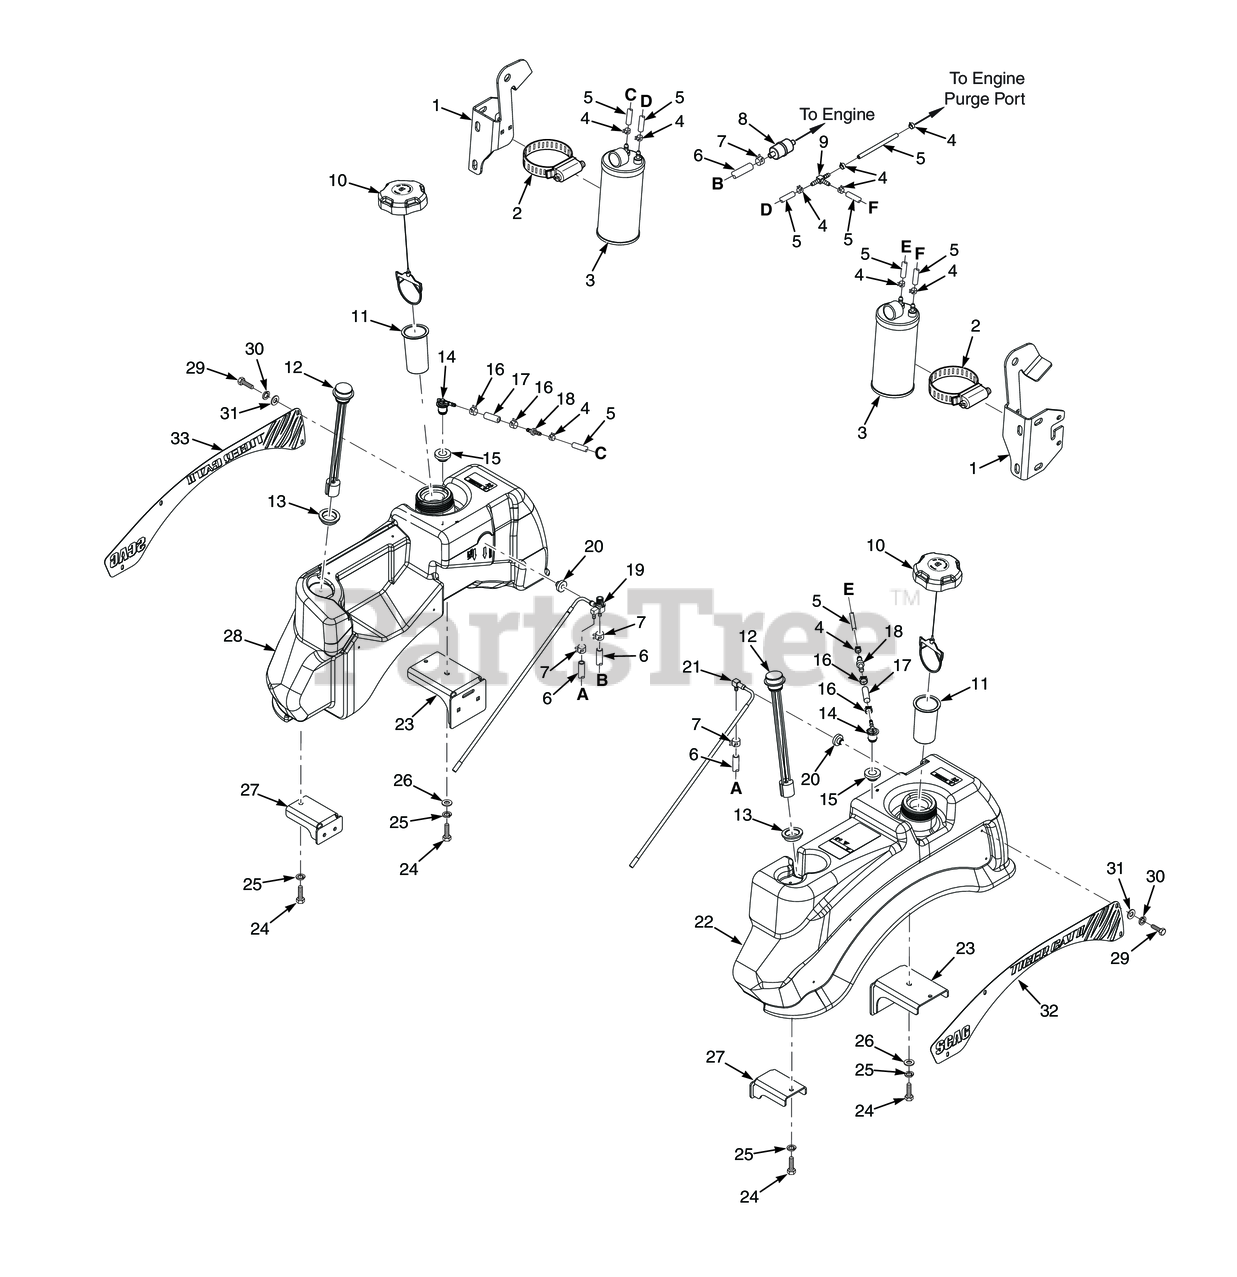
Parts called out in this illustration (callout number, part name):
1	ROPS Mount, LH
1	ROPS Mount, RH
2	Clamp, 3-1/2" Max. Dia.
3	Carbon Canister - SVR-36A / SVR-48V
4	Clamp, Vapor Recovery Hose 3/16"
5	Hose, Vapor Recovery 3/16" (order by inch)
6	Fuel Hose, 1/4" I.D. Non-Perm (791DFI Fuel Return) - Order by Inch
7	Clamp, Fuel Hose 1/4" Hose I.D.
8	Fuel Filter
9	Tee, 3/16 x 3/16 x 3/16 Union, Hose Barb
10	Fuel Cap w/ Tether (E.P.A.)
11	Tube, Fuel Tank Insert - 4"
12	Fuel Gauge Assembly
13	Grommet, Fuel Gauge
14	Remote Vent, No Valve
15	Grommet, Viton,
16	CLAMP, FUEL HOSE(KAWASAKI ONLY)
17	Hose, 1/4" Vapor Recovery (order by inch)
18	Mender, 1/4 x 3/16 w/0.02 Hole
19	Fuel Tube Assembly, Includes Valve
20	Bushing, 0.56" Dia. Viton
21	Fuel Tube Assembly, LH
22	Fuel Tank Assembly, LH (incl. # 12, 14, 15, 20, 21, 29, 30, 31, 32)
23	Mounting Bracket, Fuel Tank Rear
24	BOLT, SERRATED FLANGE HEX HEAD 5/16-18 X 3/4"
25	Lockwasher, 5/16 (.317 x .586 x .078) Helical Spring
26	Flatwasher, 5/16-.375 x .875 x .083 (35BV & 37BV-EFI)
27	Mounting Bracket, Fuel Tank Front
28	Fuel Tank Assembly, RH (incl. #12, 14, 15, 19, 20, 29, 30, 31, 33)
29	Bolt, Hex Head 1/4-20 x .5" Battery, (Not Available Through Scag)
30	Lockwasher, 1/4� Spring
31	Flatwasher, 1/4 (.258 x .500 x .0598)
32	Logo, Scag Tiger Cat II (RH)
33	Logo, Scag Tiger Cat II (LH)
